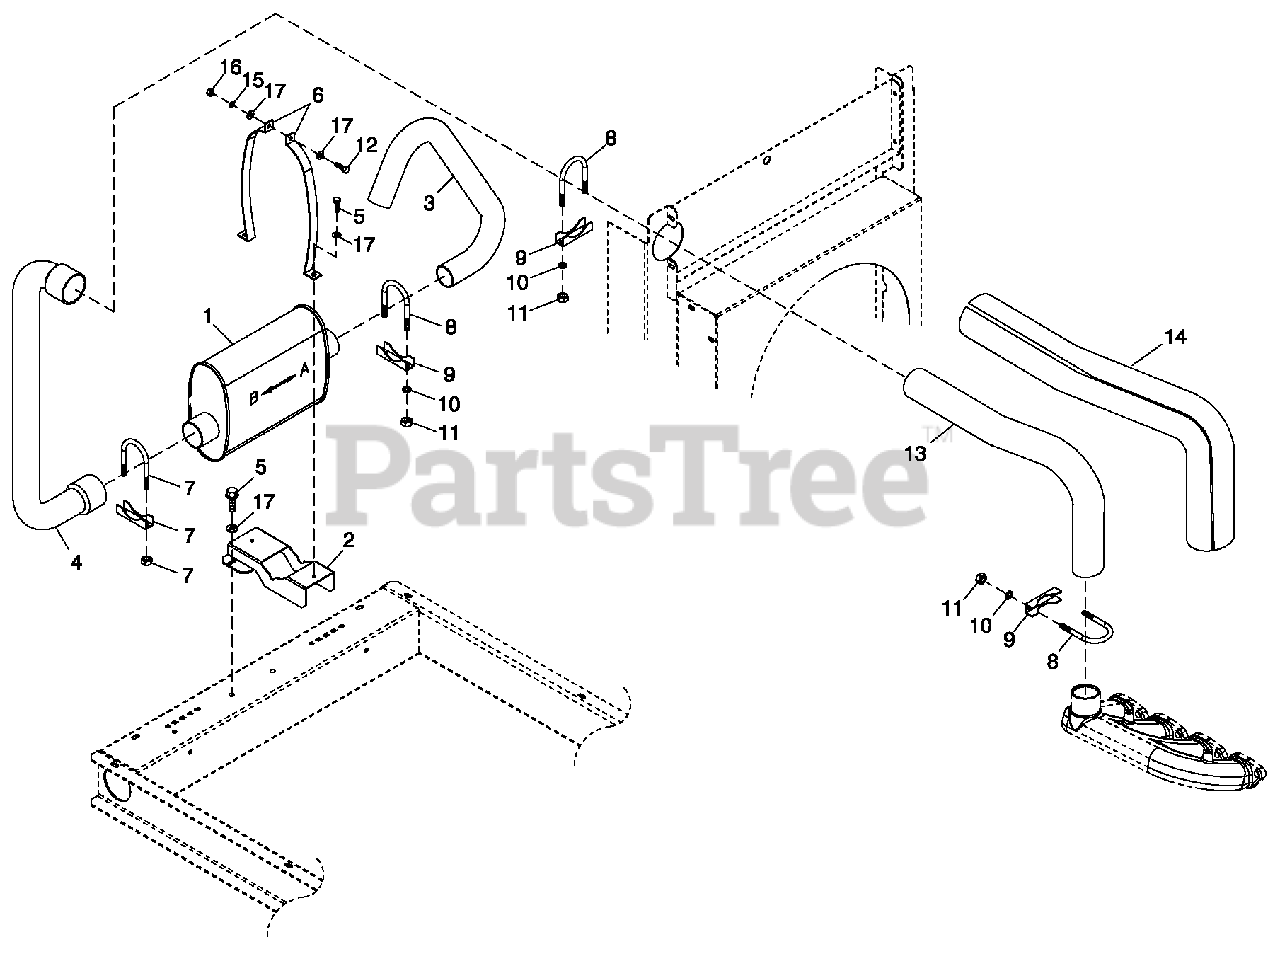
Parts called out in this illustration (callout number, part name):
1	MUFFLER C1
2	MUFFLER SADDLE
3	PIPE EXHAUST OUTLET
4	PIPE EXH INLET MUFLR SIDE 1.5L
5	SCREW HWHTF M6-1.0 X 16
6	MUFFLER STRAP
7	BOLT U 5/16-18 X 2-1/4
8	BOLT U 5/16-18 X 2.09
9	SADDLE 2 INCH
10	WASHER LOCK M8-5/16
11	NUT HEX 5/16-18 STEEL
12	SCREW HHC M6-1.0 X 30 G8.8
13	EXHAUST PIPE 1.6L
14	EXHAUST BLANKET 600MM LONG
15	WASHER LOCK M6-1/4
16	NUT HEX M6 X 1.0 G8 YEL CHR
17	WASHER FLAT 1/4-M6 ZINC
